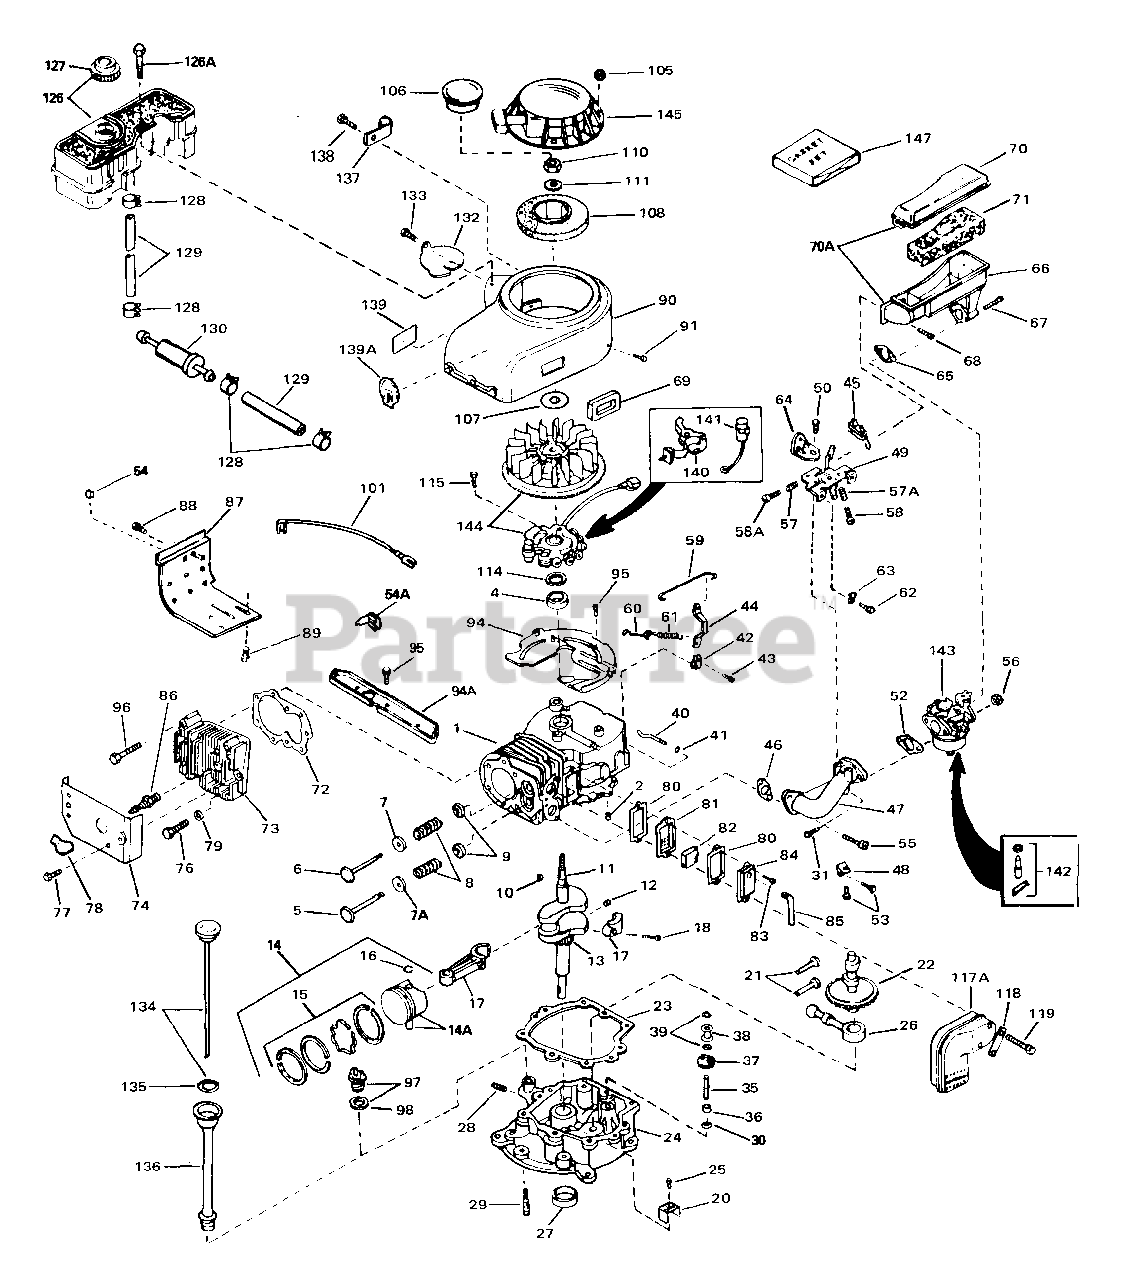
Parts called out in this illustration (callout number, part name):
1	"Cylinder Assy.
2	Pin, Dowel
4	Seal, Oil
5	Valve, Intake (Std.)
5	Valve, Intake (1/32" oversize)
6	Valve, Exhaust (Std.)
6	Valve, Exhaust (1/32" oversize)
7	Cap, Upper valve spring (Exhaust)
7A	Cap, Upper valve spring (Intake)
8	Spring, Valve
9	Cap, Lower valve spring
10	Key, Flywheel
11	Crankshaft Assy.
12	Pin, Crankshaft gear
13	Gear, Crankshaft
14	Piston, Pin & Ring Assy. (Std.) (3-3/ 16")
14	Piston, Pin & Ring Assy. (.010 oversi ze)
14	Piston, Pin & Ring Assy. (.020 overs ize)
14A	Piston & Pin Assy. (Std.) (3-3/16")
14A	Piston & Pin Assy. (.010 oversize)
14A	Piston & Pin Assy. (.020 oversize)
15	Ring Set, Piston (Std.) (3-3/16")
15	Ring Set, Piston (.010 oversize)
15	Ring Set, Piston (.020 oversize)
16	Ring, Piston pin retaining
17	Rod Assy., Connecting
18	Bolt, Connecting rod
20	Screen, Oil filter
21	Lifter, Valve
22	Camshaft (Mech. Compression Release)
23	Gasket, Mounting flange
24	Flange Assy., Mounting
26	Pump Assy., Oil
27	Seal, Oil
28	Plug, Drain (3/8-18 sq. hd.)
35	Shaft, Mechanical governor
36	Spacer, Governor gear
37	Gear Assy., Governor
38	Spool, Governor
39	Ring, Retaining
40	Rod, Governor
41	Washer, Flat
42	Clamp, Governor lever
43	Screw, Hex washer hd., 8-32 x 5/16
44	Lever, Governor
46	Gasket, Intake pipe
47	Pipe, Intake
48	Bracket, Intake pipe
49	Control Assy., Speed
52	Gasket, Carburetor
56	Nut & Lockwasher Assy.
57	Spring, Speed adj. screw
58A	Screw, Hex hd., 10-32 x 1 (Drilled th ru)
59	Link, Throttle
60	Link, Governor spring
61	Spring, Governor
63	Clip, Conduit
64	Bracket, Air cleaner
65	Gasket, Air cleaner
67	Screw, Fil. hd. Sems, 10-32 x 1-29/32
69	Gasket, Air cleaner to blower housing
70A	Cover Assy., Air cleaner
71	Element, Air cleaner
72	Gasket, Cylinder head
73	Head, Cylinder
74	Cover, Cylinder head
76	Screw, Hex flange hd., 5/16-18 x 1-1/ 2
77	Screw, Hex washer hd. taptite, 1/4-20 x 1/2
77	Screw, Hex washer hd. spinlock
80	Gasket, Breather
81	Body, Breather
82	Element, Breather
84	Cover, Breather
85	Tube, Breather
86	Plug, Spark (Champion J-8 or equivale nt)
86	Resistor Spark Plug
87	Extension, Blower housing
89	Screw, Hex hd. Sems, 1/4-20 x 1/2
90	Housing, Blower
91	Screw
94	Baffle, Blower housing
97	Plug, Oil filler
98	Gasket, Filler plug
101	Wire, Ground (One female & one male f itting)
106	Plug, Screen
107	Washer, Flat
108	Hub & Screen Assy., Starter
110	Nut, Hex, 1/2-20
111	Washer, Belleville
114	Gasket, Stator
120	Muffler Adapter Kit
121	Screw, Fil. hd., 5/16-18 x 3/4
122	Gasket, Exhaust flange
127	Cap, Fuel filler (Red Plastic) (Spurt
128	Clamp, Fuel line
129	Line, Fuel (Braided 8-1/4")
130	Filter, Inline fuel
132	Cover, Starter bubble
139	Decal, Instruction
140	Contact Assy., Breaker
141	Condenser
142	Inlet Needle, Seat & Clip Assy.
143	Carburetor
144	Magneto, Tecumseh (w/ring gear) (12 V olt)
147	Gasket Set
